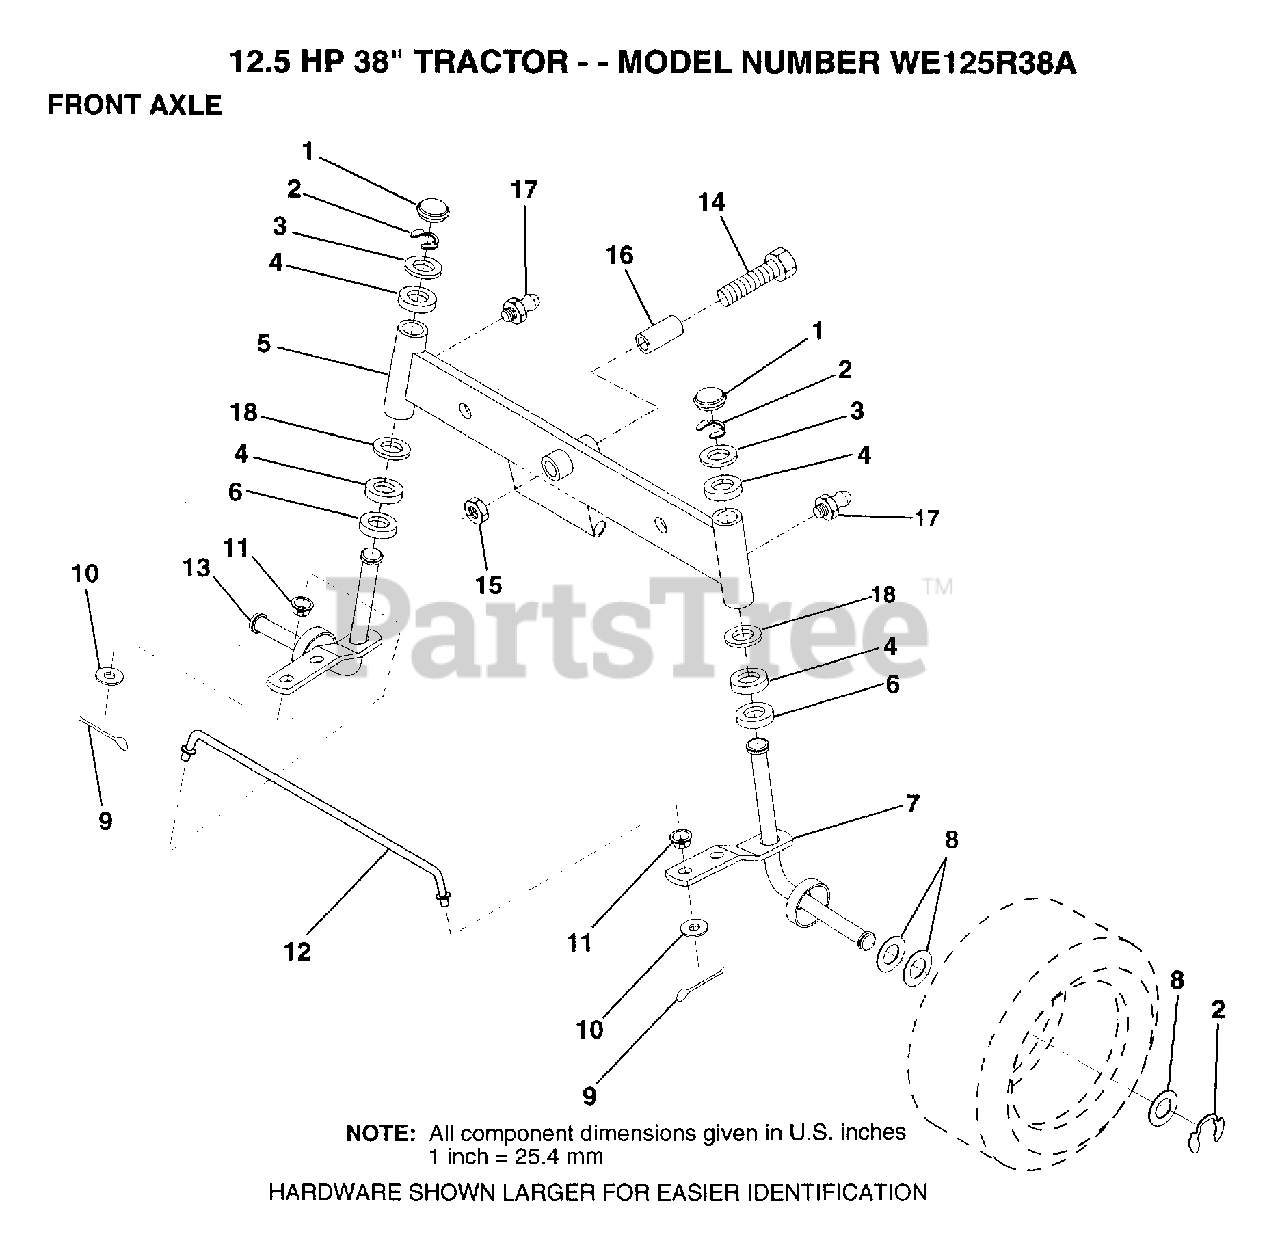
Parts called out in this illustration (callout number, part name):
1	CAP
2	RING
3	WASHER
4	COL. SRTG. BEAR.
6	WASHER .T
7	SPINDLE ASM RH
8	WASHER
9	COTTER PIN
10	WASHER
11	BUSHING.DRAGLINK
12	TIE ROD
13	SPINDLE ASM LH
14	BOLT HEX 5/8-11
15	"NUT-LOC,FLANGE LT"
16	BEARING
17	ZERK M
18	WASHER
